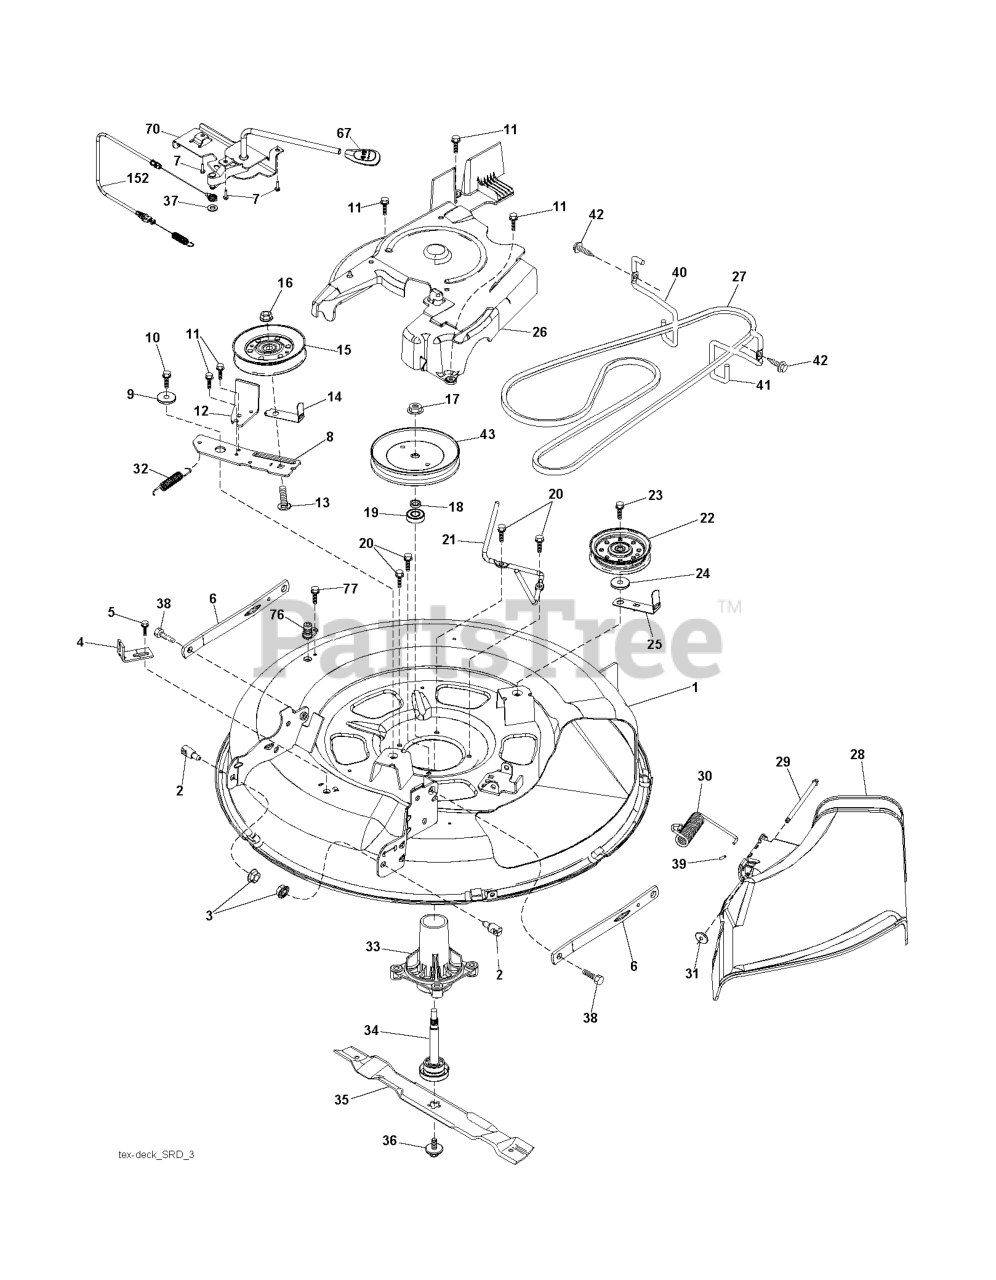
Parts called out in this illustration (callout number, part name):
1	DECK.WELDMENT.30".GREY
2	STUD.FASTNER.W/ANTI-ROTATE
3	NUT LOCK HEX FLANGE 5/16-18
4	BRACKET.CLUTCH.CABLE
5	BOLT.5/16HEX.WHS.HD
6	ARMS.SUSP.MOWER.REAR.SRD
7	SCREW.#10 X 0.750.BOS
8	ARM.IDLER.30"SRD
9	SPACER.RETAINER
10	SCREW 3/8-16X1
11	SCREW.1/4-20X5/8
12	RP ARM.BRAKE.MOWER.38"LH.TEX
13	BOLT.3/8-16X1.50
14	KEEPER, BELT IDLER
15	PULLEY.IDLER.4.25
16	NUT LOCK FLG 3/8-16 UNC
17	NUT.FLANGE.LOCK.TOP
18	WASHER.SPACER.MANDREL
20	SCREW, WASHER HEAD
21	KEEPER.BELT.MANDREL.30"
22	PULLEY.IDLER.FLAT.46.PR.DR.
23	SCREW LT
24	WASHER
25	KEEPER.BELT.30"SRD
26	COVER.ASM.MANDREL.30"
27	V-BELT.DRIVE.MOWER.30"
28	SHIELD.DEFLECT.MWR.30S.BLACK
29	PIN.HINGE.30".SRD
30	SPRING.TORSION.DEFLECT
31	NUT PUSH M
32	SPRING RETURN
33	RP.HOUSING.MANDREL.4PT.
34	SHAFT.ASM.MDRL.N/GREASE.38
35	BLADE, MULCH.LRV30
36	BOLT.WASHER.ASM.7/16-2
37	WASHER
38	BOLT.SHOULDER
39	CAP-SLEEVE LT
40	KEEPER.BELT.ENGINE.LH.LT.SRD
41	KEEPER.BELT.ENGINE.RH.LT.SRD
42	SCREW, 3/8-16X3/4
43	PULLEY, MANDREL 6.5 PD
67	HANDLE.CLUTCH.CABLE.LT
70	CLUTCH.ASM.MANUAL.LT.PRED
76	PORT.WASHOUT
77	SCREW.1/4-20X5/8
152	CABLE.CLUTCH.MANUAL.
